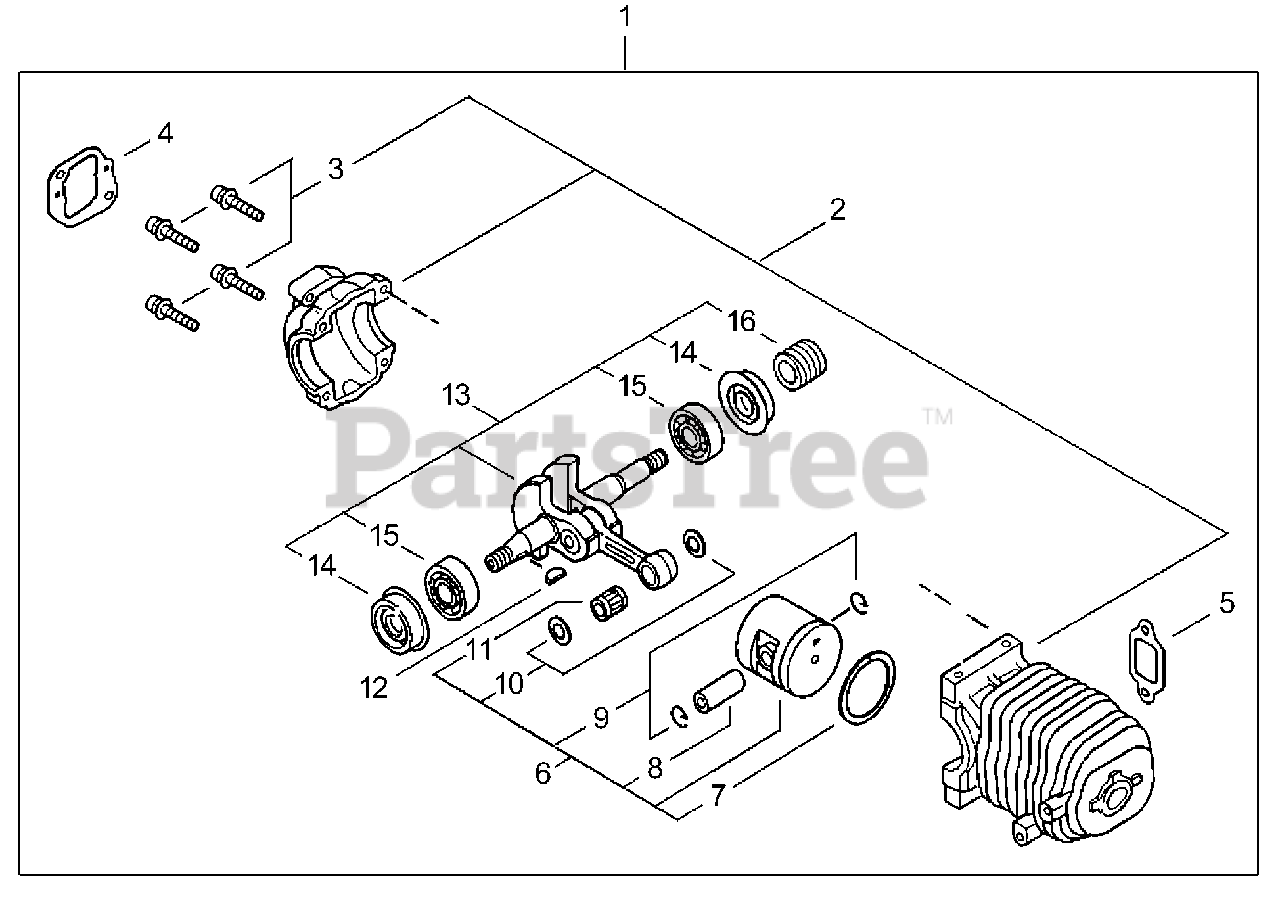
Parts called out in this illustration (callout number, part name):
1	SHORT BLOCK -- SB1018
2	CYLINDER/CRANKCASE KIT
3	SCREW - 5X25
4	GASKET, INTAKE
5	GASKET, EXHAUST
6	PISTON KIT
7	RING, PISTON
8	PIN, PISTON
9	RING, RETAINING
10	SPACER, PISTON
11	BEARING, NEEDLE
13	CRANKSHAFT ASSY
14	SEAL, OIL - 12
15	BEARING, BALL - 6201
16	GEAR - WORM
